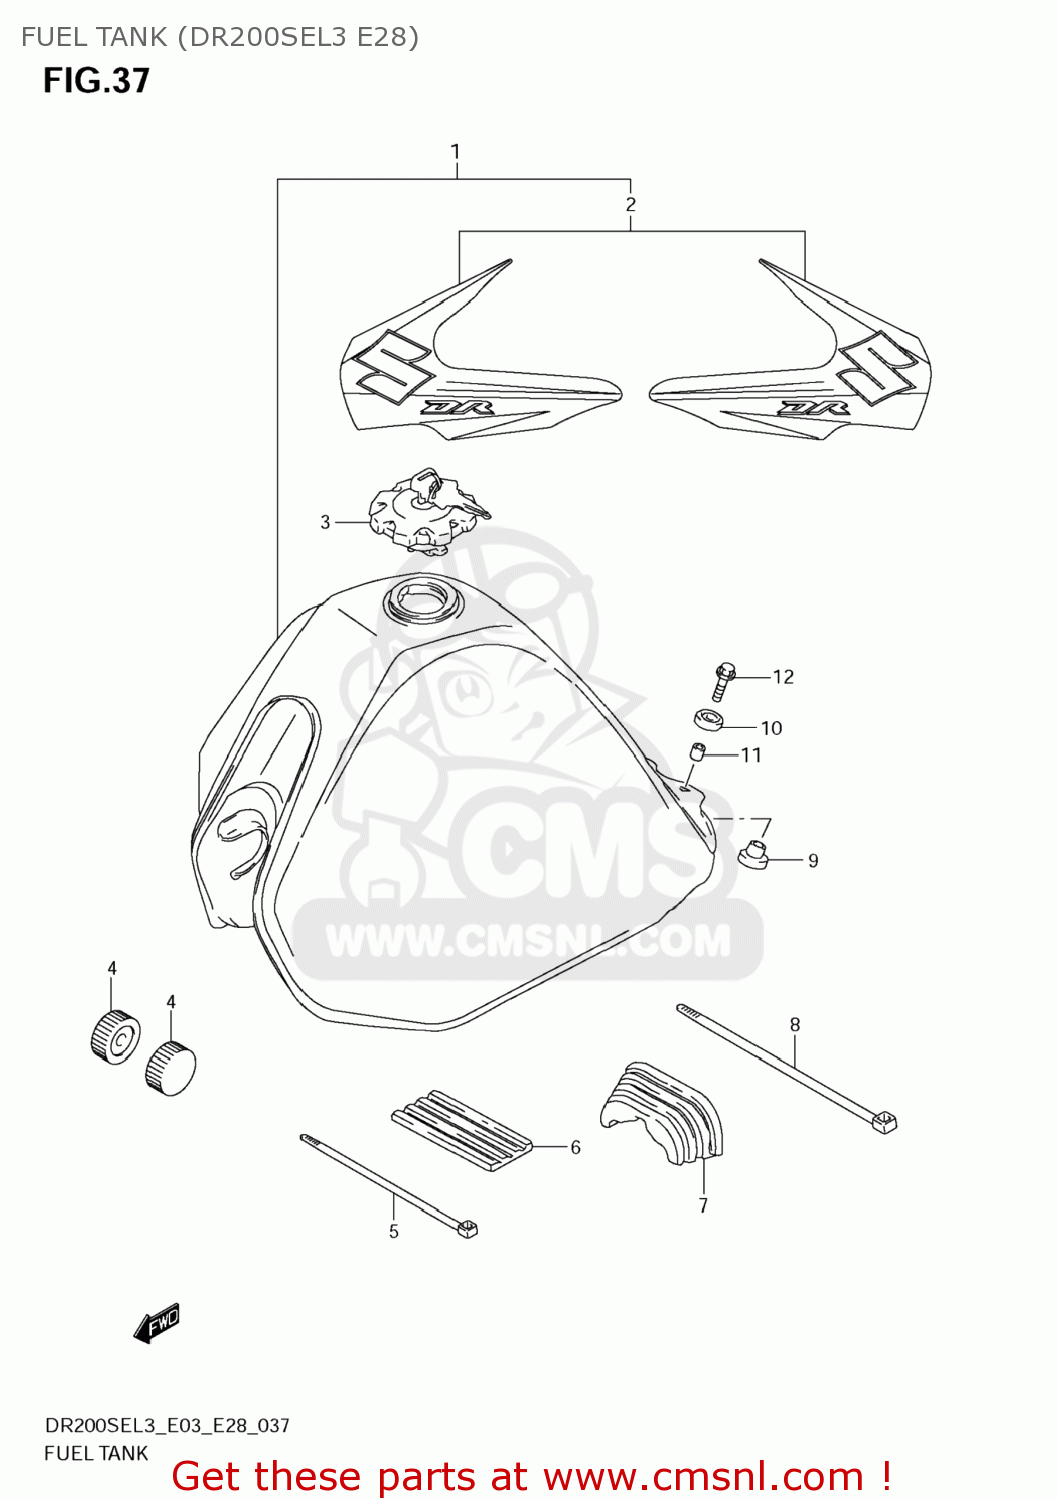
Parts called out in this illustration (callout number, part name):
1	TANK ASSY,FUEL(BLACK)
2	TAPE SET,FUEL TANK
3	CAP SET,FUEL TANK
4	CUSHION
5	CLAMP(L:250)
6	CUSHION,FUEL TANK UPR FR
7	CUSHION,FUEL TANK RR
8	CLAMP(L:300)
9	CUSHION
10	CUSHION
11	SPACER(6.5X9X18)
12	BOLT
